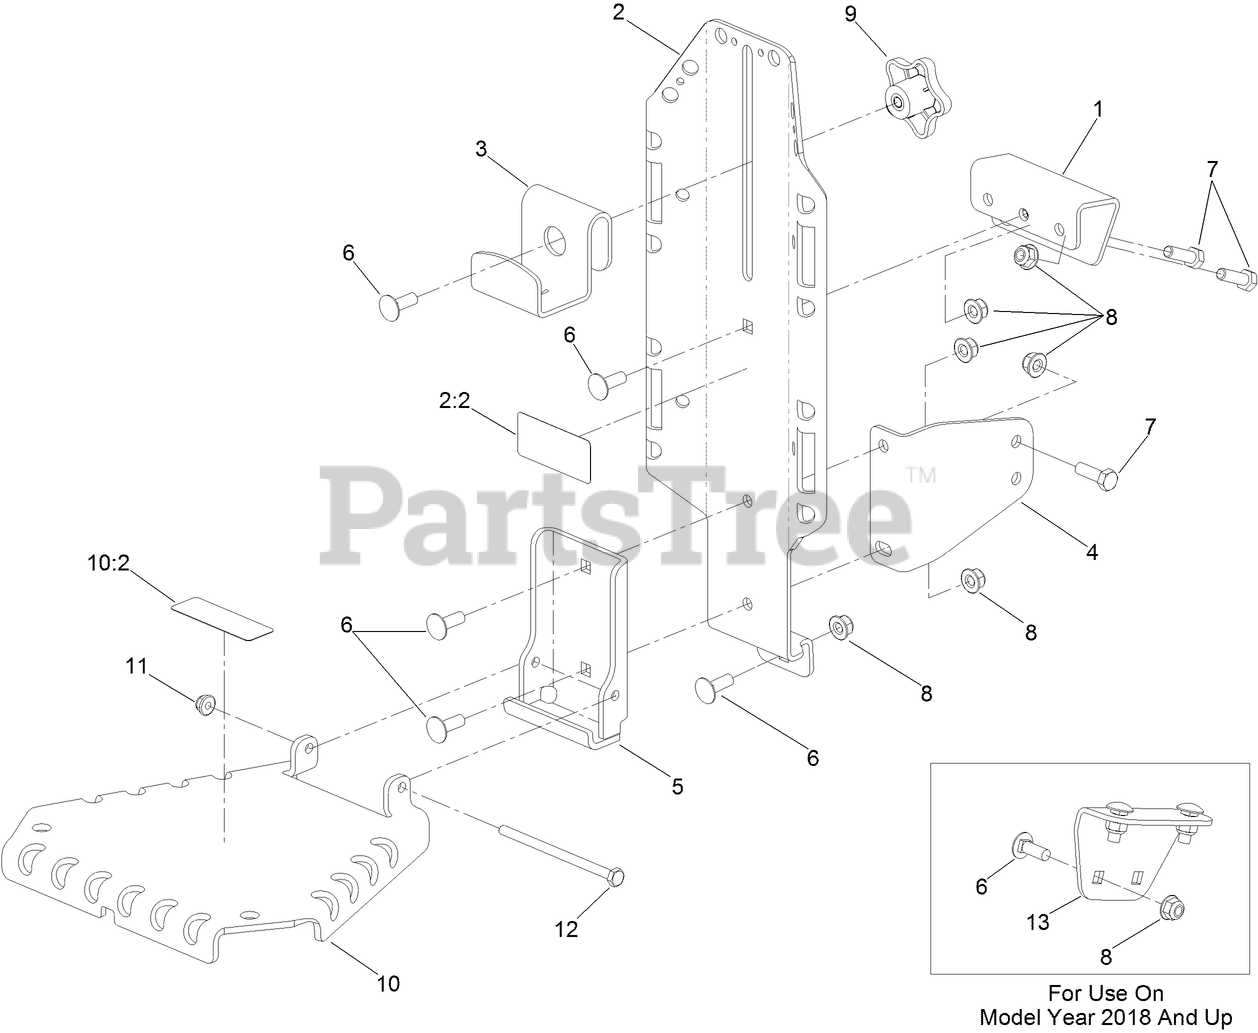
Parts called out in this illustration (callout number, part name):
1	MOUNT-BUCKET, UPPER
2	MOUNT BRACKET ASM
2:2	DECAL-WEIGHT, MAXIMUM
3	BRACKET-TOP
4	BRACKET-SUPPORT, LOWER
5	BRACKET-SUPPORT, HINGE
6	BOLT-CARR
7	SCREW-HH
8	NUT-HF, NI
9	KNOB-HANDLE
10	SUPPORT BRACKET ASM
10:2	DECAL-NO STEP/RIDERS
11	NUT-HF
12	SCREW-HH
13	BRACKET-SUPPORT, INNER
99	STRAP-RATCHET, 3 FT (RED)
